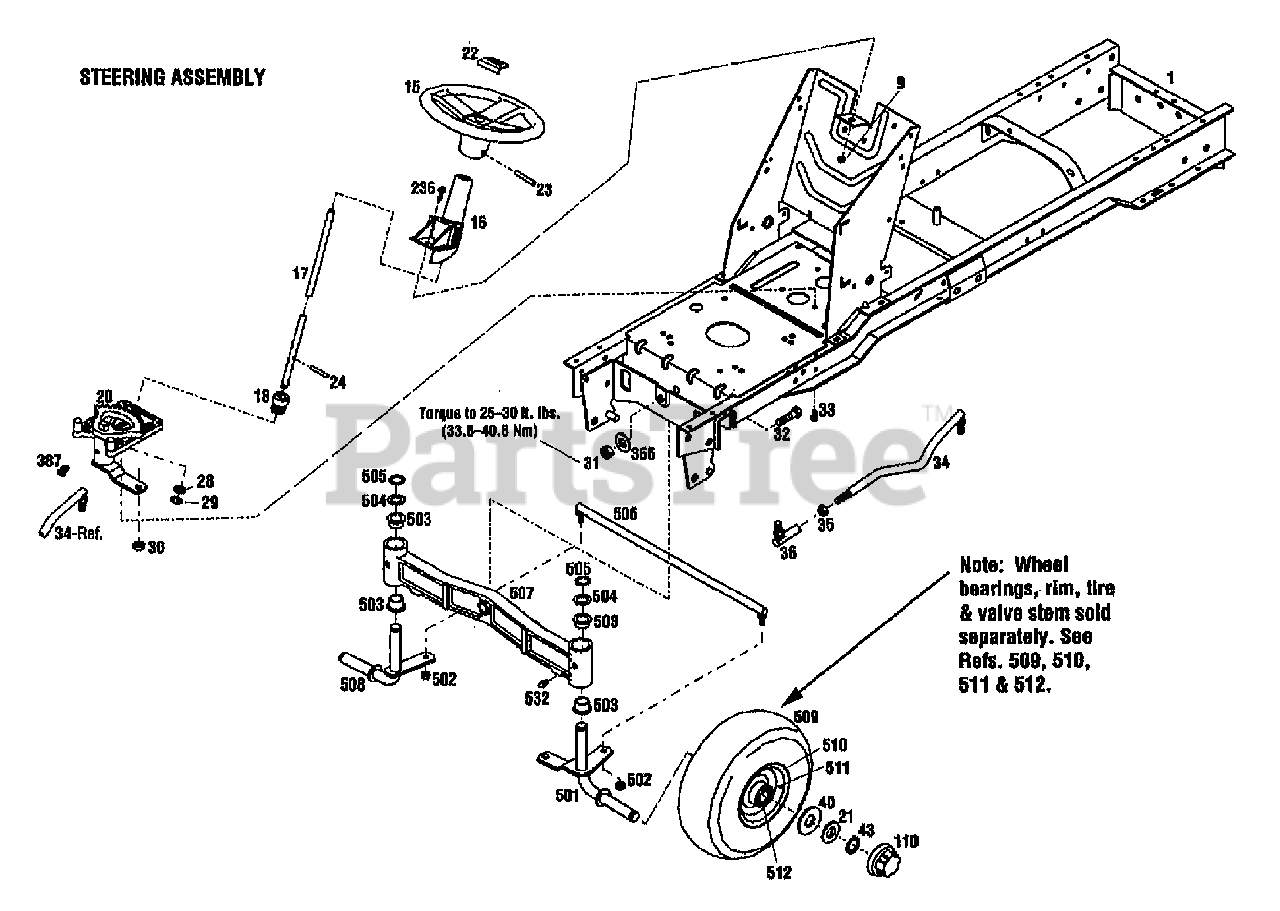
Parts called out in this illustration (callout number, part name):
9	NUT-HFLK 5/16-18 ZP
15	WHEEL-STEERING
16	SUPPORT-STEERING SHAFT
18	GEAR-PINION
20	ASSM-STEERING GEAR
21	WASHER-THRUST
22	CAP-STEERING
23	PIN-ROLL .25X2.25
24	PIN-ROLL 1/4 X 1-1/4
28	WASHER-1.0X.64X.09
29	RING-RETAINING
30	NUT-HEX/JAM 1/2-20
31	NUT-H/LK 5/8-11
32	SCR-HH
33	SCR-HFLK 5/16-18X.75
34	LINK-DRAG
35	NUT-JAM
36	JOINT-BALL
40	WASHER-SPECIAL .75X2.5
43	RING-HEAVY EXT HD 1.0 ID
110	CAP-HUB
236	SCR-HFLK 5/16-18X.75 ZP
366	WASHER-1.75X.687X.134 ZP
387	FITTING-GREASE 90 DEGREE
501	SPINDLE-WHEEL LH
502	NUT-LOCK
503	BEARING-FLANGE
504	WASHER-THRUST
505	RING-HEAVY EXT HD 1.0 ID
506	KIT-TIE ROD W/HDW
507	AXLE-FRONT
508	SPINDLE-WHEEL RH
509	TIRE-16X6.50-8
510	RIM-WHEEL
511	STEM-VALVE
512	BEARING-BALL
532	FITTING-GREASE 1/4-28X2.00
